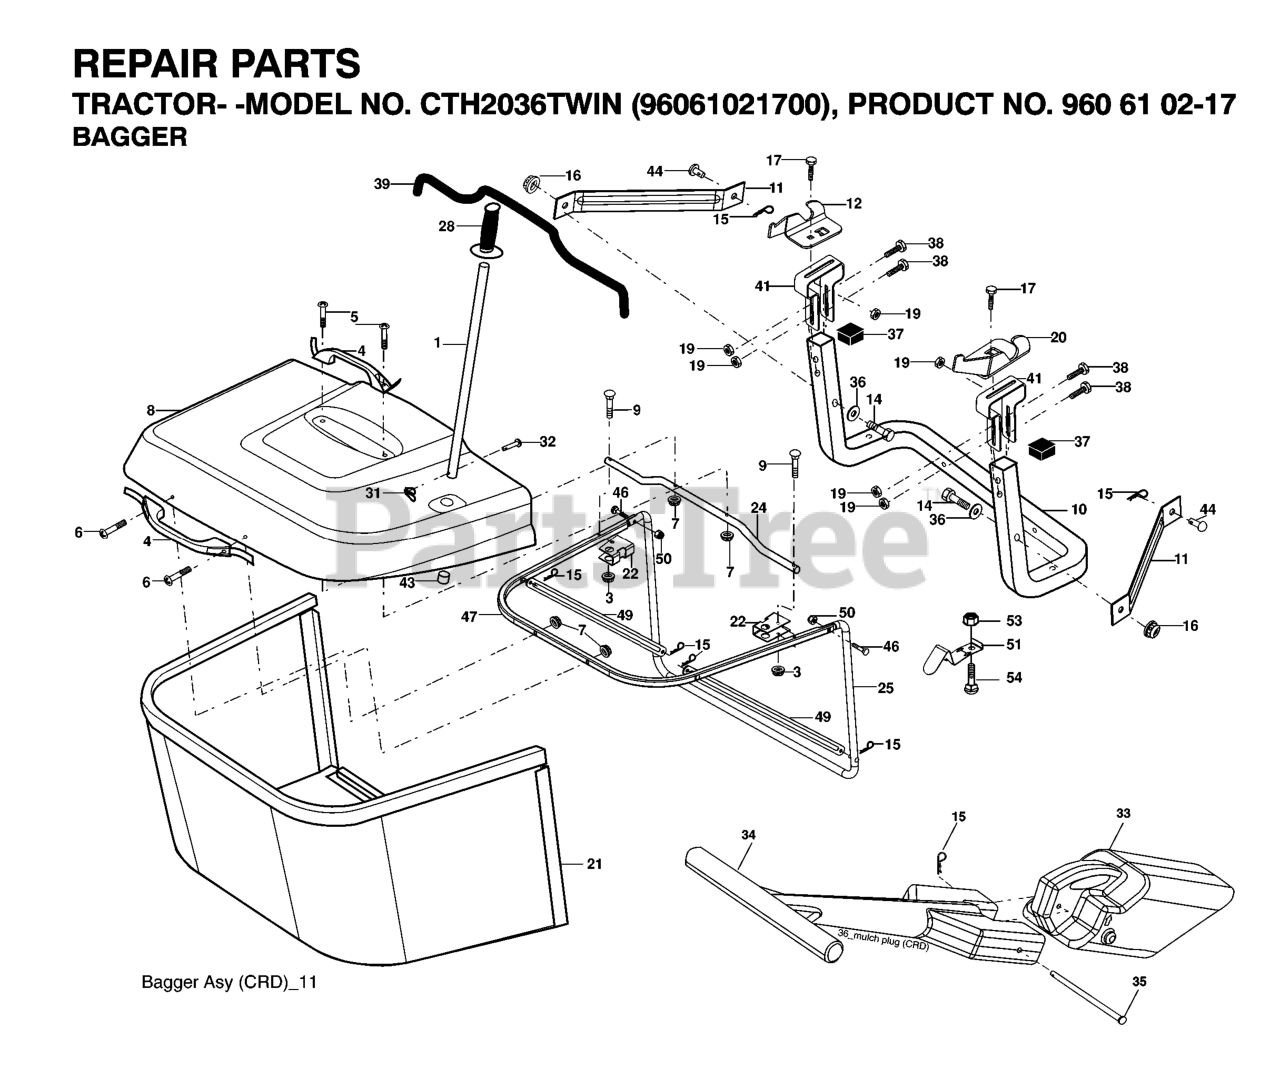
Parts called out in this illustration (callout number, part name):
1	TUBE HANDLE
3	NUT T
4	HANDLE.BAGGER.W/LVRS.BLK.CRD
5	SCREW.PAN.HEAD
6	REPL BY 532 75 00-29
8	COVER.PNT.BGR.CRD.WSLOTS.MS668
9	Bolt Carriage 1/4-20 x 2.25d x Gr.5
10	TUBE
11	BRACKET.SUPPORT.UPPER.BAG.CRD
12	BRKT PIVOT
14	BOLT-HEX EAK
15	RETAINER-SPRNG RB
16	NUT LOCK FLG 3/8-16 UNC
17	RP BOLT 5/16-18 X3/4 ZN/YEL GR
19	NUT LOCK HEX FLANGE 5/16-18
20	BRKT.PIVOT.RH.CRD
21	BAGGER.ASM.CRD.2007
22	BRKT.SIDE.BAG.CRD
24	TUBE.PIVOT.BAG.CRD.BLACK
25	PIPE
28	GRIP.HANDLE.BLACK
31	RETAINER CLIP
32	RIVET,DRILLED
33	PLUG.MULCHER.92 CRD
34	HANDLE.MULCHER.92.CRD (2 2)
36	WASHER
37	Plug Support Bagger CRD
38	BOLT.5/16-18X2.5
39	SEAL.TRIM.37'
41	BRKT.VERT.ADJ.BAGGER.CRD
43	PLUG, TUBING END
46	BOLT.CARRIAGE.5/16-18
47	PIPE
49	ROD
50	NUT.71038.31-18.HEX.NYLOCK
51	LATCH
53	NUT
54	BOLT
